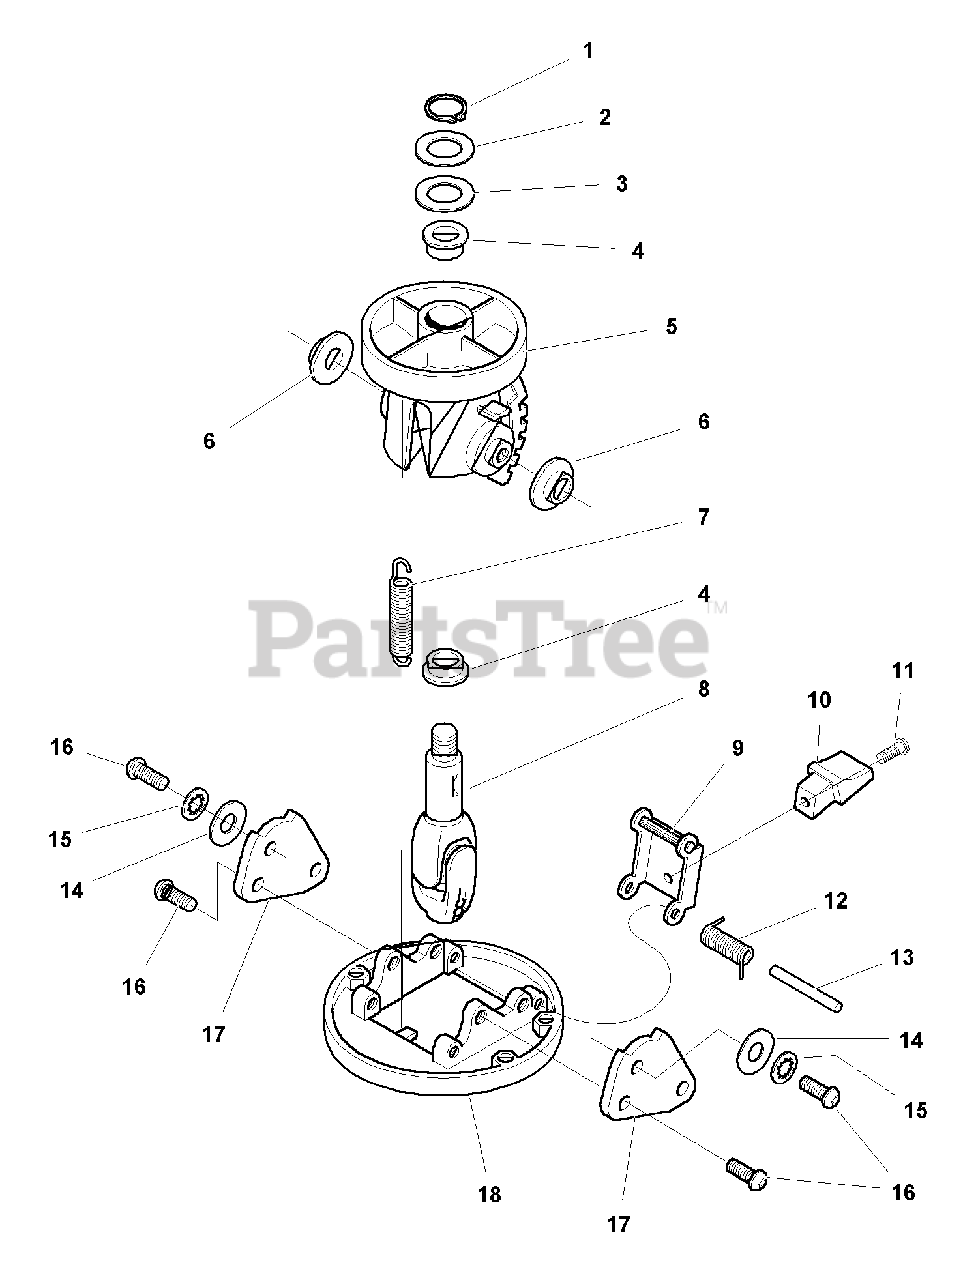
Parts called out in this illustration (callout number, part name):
1	RING, Retaining
3	WASHER, Spring Wave
5	SUPPORT, Wheel Shaft
7	SPRING, Tilt
8	ASSEMBLY, Wheel Shaft
9	ASSEMBLY, Latch
10	LEVER, Release
12	SPRING, Latch
13	SHAFT, Latch
15	LOCKWASHER, Internal Tooth
17	PLATE, Support
18	BASE
